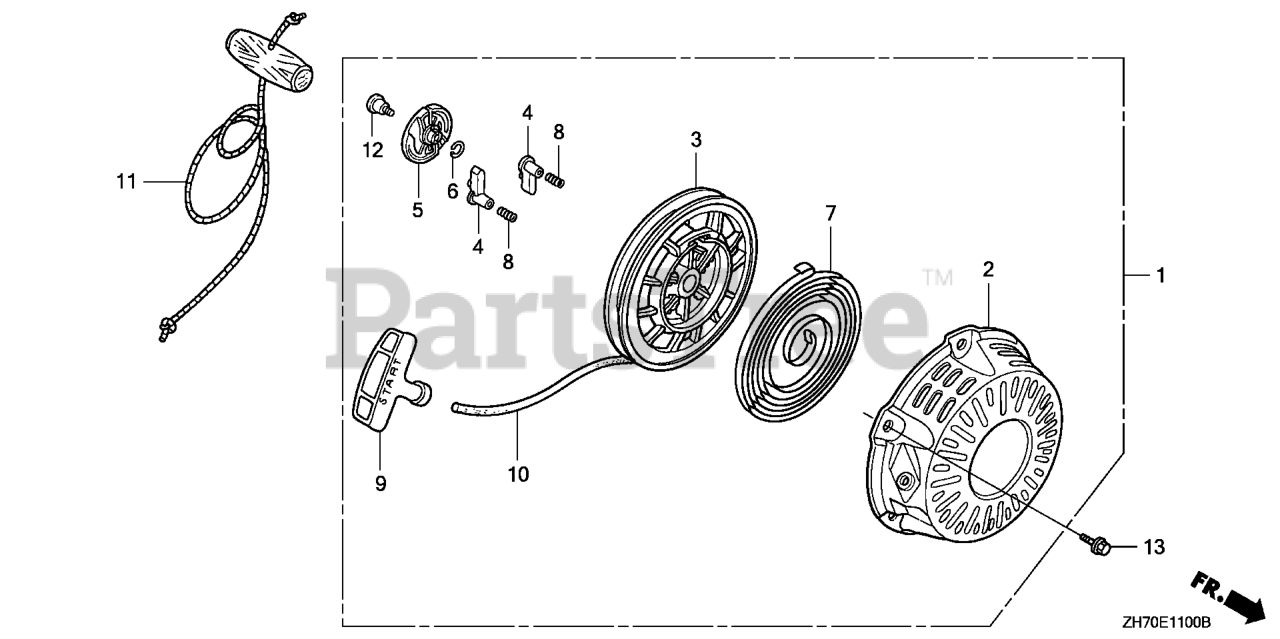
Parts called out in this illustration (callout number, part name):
1	STARTER ASSY., RECOIL *R280* (POWER RED)
1	STARTER ASSY., RECOIL *NH1* (BLACK) (ENGINE NO.)
2	CASE, RECOIL STARTER *R280* (Honda Code 7346836). (POWER RED)
2	CASE, RECOIL STARTER *NH1* (Honda Code 4193058). (BLACK)
3	REEL, RECOIL STARTER (NATURAL) (ENGINE NO.)
4	RATCHET, STARTER
5	GUIDE, RATCHET (ENGINE NO.)
6	SPRING, FRICTION (ENGINE NO.)
7	SPRING, RECOIL STARTER
8	SPRING, RETURN (ENGINE NO.)
9	GRIP, STARTER
10	ROPE, RECOIL STARTER (#5X55")
12	SCREW, SETTING (ENGINE NO.)
13	BOLT, FLANGE (6X10)
